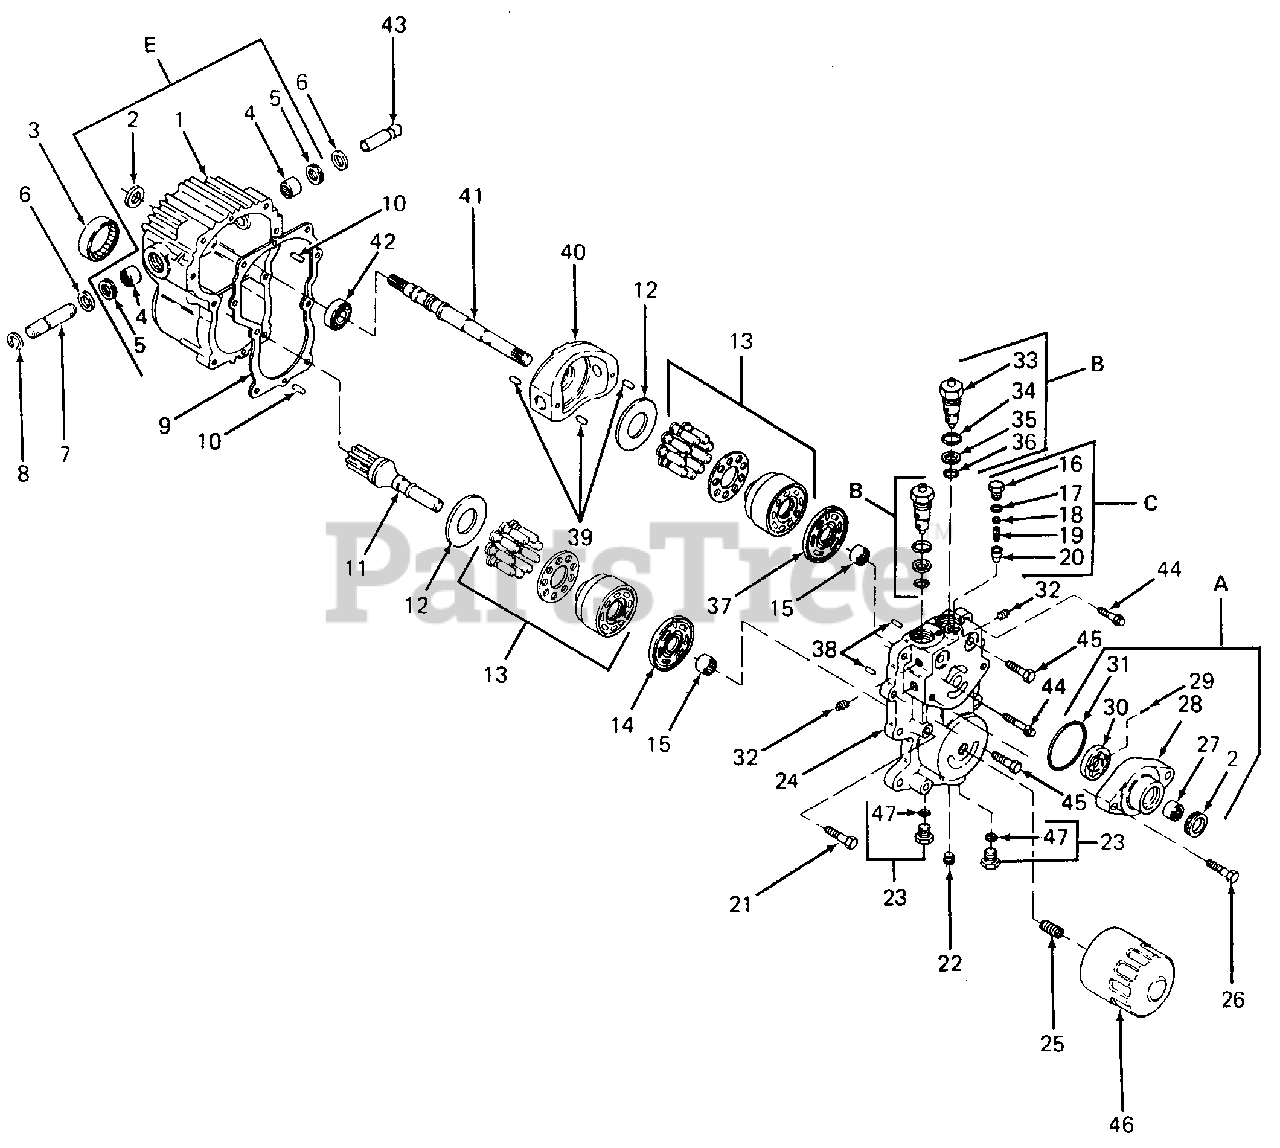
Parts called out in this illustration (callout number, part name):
1	Housing, Transmission
2	Seal, Lip
3	Bearing, Roller
4	Bearing, Needle
5	Seal, Lip
7	Shaft, Trunnion
8	Ring, Retaining
9	Gasket
10	Pin
11	Shaft, Motor
12	Plate, Thrust
13	Block, Cylinder
14	Plate, Valve
15	Bearing, Roller
16	Plug
17	O-Ring
18	Kit, Shim Pack
19	Spring, Relief Valve
20	Cone, Relief Valve
24	Center Section
27	Bearing, Needle
28	Charge Pump Housing
30	Gerotor
33	Valve
35	Ring, Back-up
37	Plate, Valve
41	Shaft, Pump
43	Shaft Assembly, Trunnion
44	Screw, 12 Point
46	Oil Filter
A	Kit, Charge Pump
B	Valve Assembly
C	Kit, Relief Valve
E	Housing Assembly
